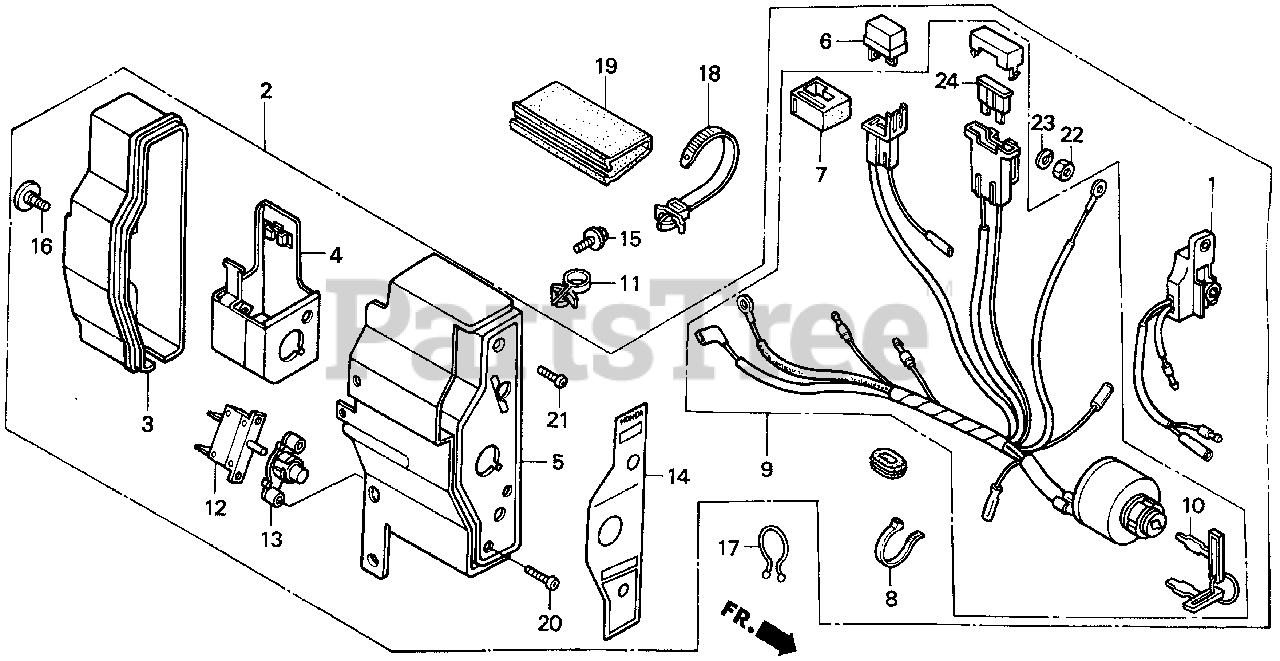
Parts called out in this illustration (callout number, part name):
1	ALERT UNIT, OIL (SEL)
2	BOX ASSY., CONTROL *R8* (EXTERNAL-ALERT) (BRIGHT RED)
2	BOX ASSY., CONTROL *T39* (GEKO BLUE)
2	BOX ASSY., CONTROL *NH105* (EXP-ALERT) (MAT BLACK)
2	BOX ASSY., CONTROL *NH105* (EXTERNAL-ALERT) (MAT BLACK)
3	CASE, CONTROL
4	BRACKET, CASE MOUNTING
5	PANEL, CONTROL *R8* (BRIGHT RED)
6	RECTIFIER ASSY., SILICON (STANLEY)
7	SUSPENSION, CONNECTOR
8	BAND
9	SWITCH ASSY., COMBINATION
10	KEY
11	HOLDER, STOP SWITCH WIRE
12	PROTECTOR, CIRCUIT (1.0A)
13	LENS ASSY., PROTECTOR
14	PANEL, CONTROL BOX (EXTERNAL)
14	PANEL, CONTROL BOX (EXTERNAL-ALERT)
15	BOLT, FLANGE (6X12) (CT200)
16	SCREW, SPECIAL (6X12)
17	CLIP, PURSE LOCK
18	STRAP, CABLE (118MM) *NH1L* (BLACK)
19	TUBE, FASTENER (30)
20	SCREW, PAN (3X12)
21	SCREW, PAN (4X12)
22	NUT, HEX. (4MM)
23	WASHER, SPRING (4MM)
24	FUSE, BLADE (5A)
25	ALERT UNIT, OIL
26	WASHER, PLAIN (4MM)
